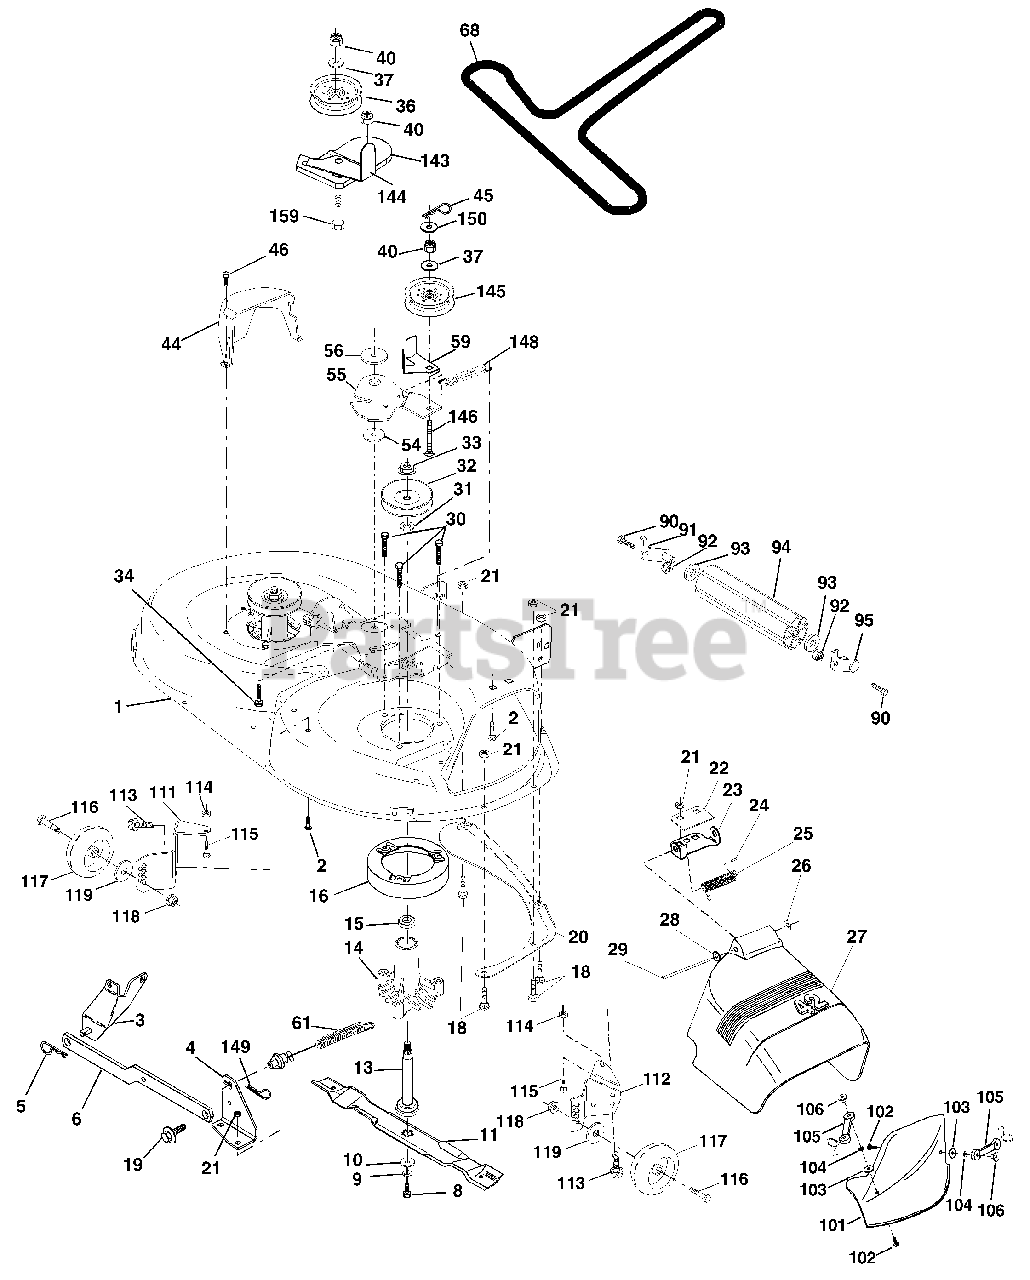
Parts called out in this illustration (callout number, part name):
1	Mower Deck Assembly, 42"
2	Bolt
3	Bracket Assembly, Sway Bar, Front
4	Bracket Sway Bar 38/42" Deck
5	Retainer Spring
6	Arm, Suspension, Rear
8	Bolt, Hex 3/8-24 x 1.25 Gr. 8
9	Washer, Lock
10	Washer, Hardened
11	Blade Mower 42" High Perf.
11	Blade, Mulching
13	Shaft Assembly, Mandrel, Vented
14	Housing, Mandrel, Vented
15	Bearing, Ball, Mandrel
18	Bolt, Carriage 5/16-18 x 5/8
19	Bolt, Shoulder
20	Baffle, Vortex
21	Nut Crownlock 5/16-18 UNC
22	Stiffener Bracket
23	Bracket, Deflector
24	Cap, Sleeve
25	Spring, Torsion, Deflector
27	Shield, Deflector
28	Washer 11/32 x 5/8 x 16 Ga.
29	Rod, Hinge
30	Screw Thdrol Washer Head
31	Washer, Spacer
32	Pulley, Mandrel
33	Nut, Toplock, Flanged
35	Fastner, Christmas Tree
36	Pulley, Idler, Flat
37	Washer 13/32 x 13/16 x 16 Gauge
40	Nut Crownlock 3/8-16 UNC
44	Guard, Mandrel, L.H.
45	Retainer
46	Screw, Thd. Roll 1/4-20 x 5/8
54	Washer, Hardened
55	Arm, Idler
56	Spacer, Retainer
59	Guard, TUV Idler
61	Spring Ext Elect Clutch 42" Dck
90	Bolt Fin Hex 3/8-16 Unc x 1
91	Bracket Asm Noseroller Lh
92	Nut Lock Hex w/Ins. 3/8-16 Unc
93	Washer 17/32 x 7/8 x 16 Ga.
94	Roller Nose 38"-50"
95	Bracket Asm Noseroller Rh
101	Mulcher Cover
102	Screw
103	Washer #10
104	Washer, Lock
105	Latch Assembly, Bagger
106	Nut, Weld
111	Bracket, Gauge, Wheel L.H.
112	Bracket, Gauge, Wheel R.H.
113	Screw Tapping 5/16-18 Unc
114	Nut, Hex, Keps 5/16-18 UNC
115	Bolt, Carriage 5/16 UNC x 1/2
116	Bolt, Shoulder
117	Wheel, Gauge
118	Nut, Centerlock 3/8-16
119	Washer 3/8 x 7/8 x 14 Gauge
121	Bracket
143	Bracket Arm Idler 42"
144	Keeper Belt 42" Clutch Cable
145	Pulley Idler Flat
146	Bolt Carriage Idler
148	Spring Return Idler
149	Retainer Spring Yellow Zinc
150	Washer 9/32 x 3/4 x 16 Ga.
159	Bolt Rdhd Sqn 3/8-16 UNC x 1- 3/4
